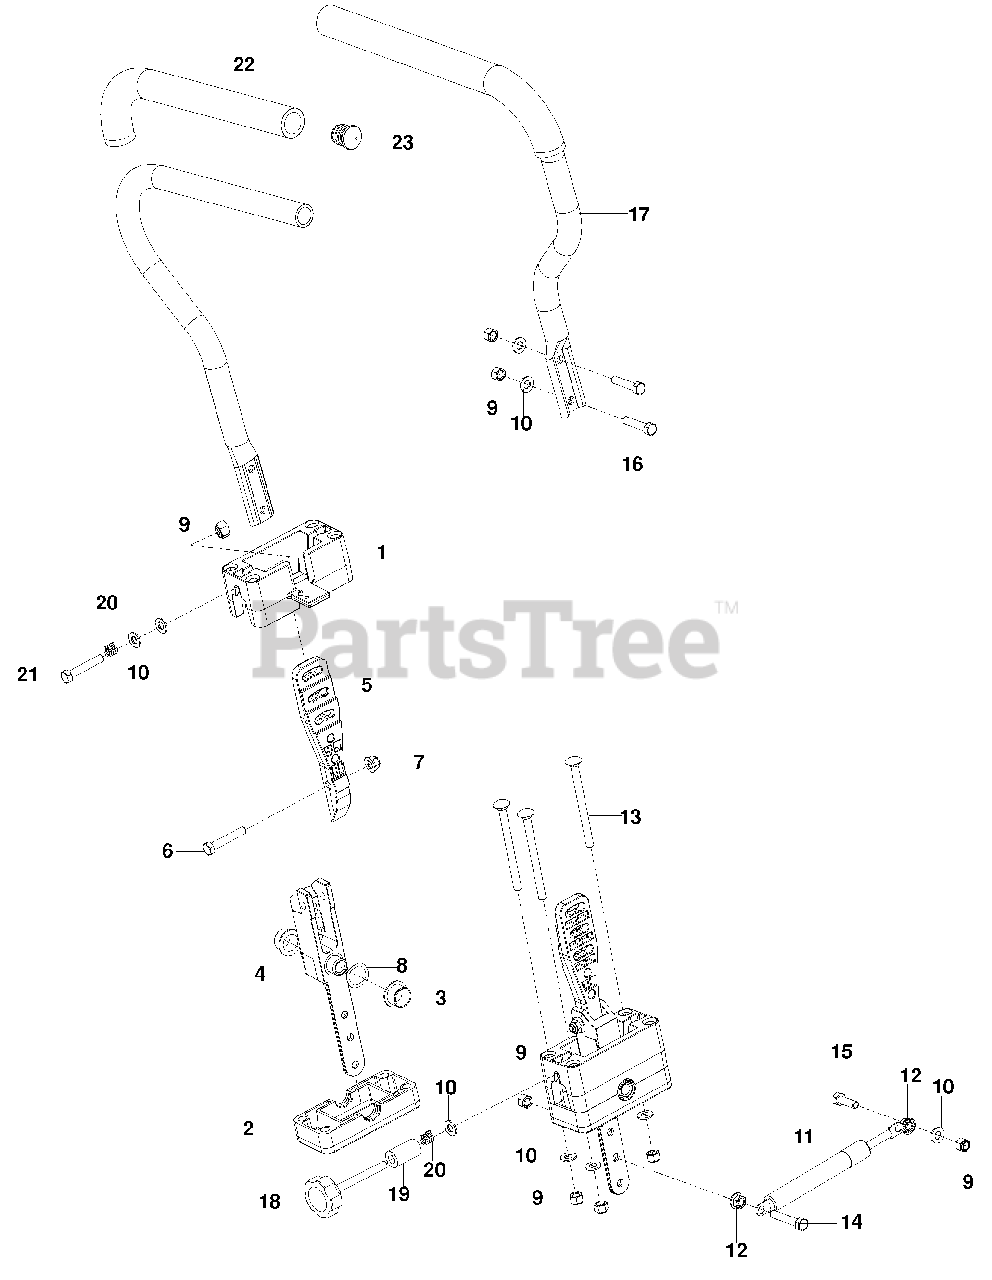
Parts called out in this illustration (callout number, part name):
1	Block, Upper
2	Block, Lower
3	Bearing, Flange
4	Pivot Section, Drive
5	Mount, Drive Control
6	Hcs 5/16-18 X 1 3/4
7	Nut 5/16-18 Flange Nyloc
8	Washer, .825 X 1.087 Wave
9	Nut 5/16-18 Hex Nyloc
10	Washer 5/16 Sae Flat
12	Nut 5/16-18 Hex Whizlk
13	Rhsnb 5/16-18 X 4
14	Hcs 5/16-18 X 1 3/4 Tpblt
15	Hcs 5/16-18 X 1
16	Hcs 5/16-18 X 1 1/2
17	Lever, W/Grip
21	Hcs 5/16-18 X 2 Tpblt
22	Grip, Foam
